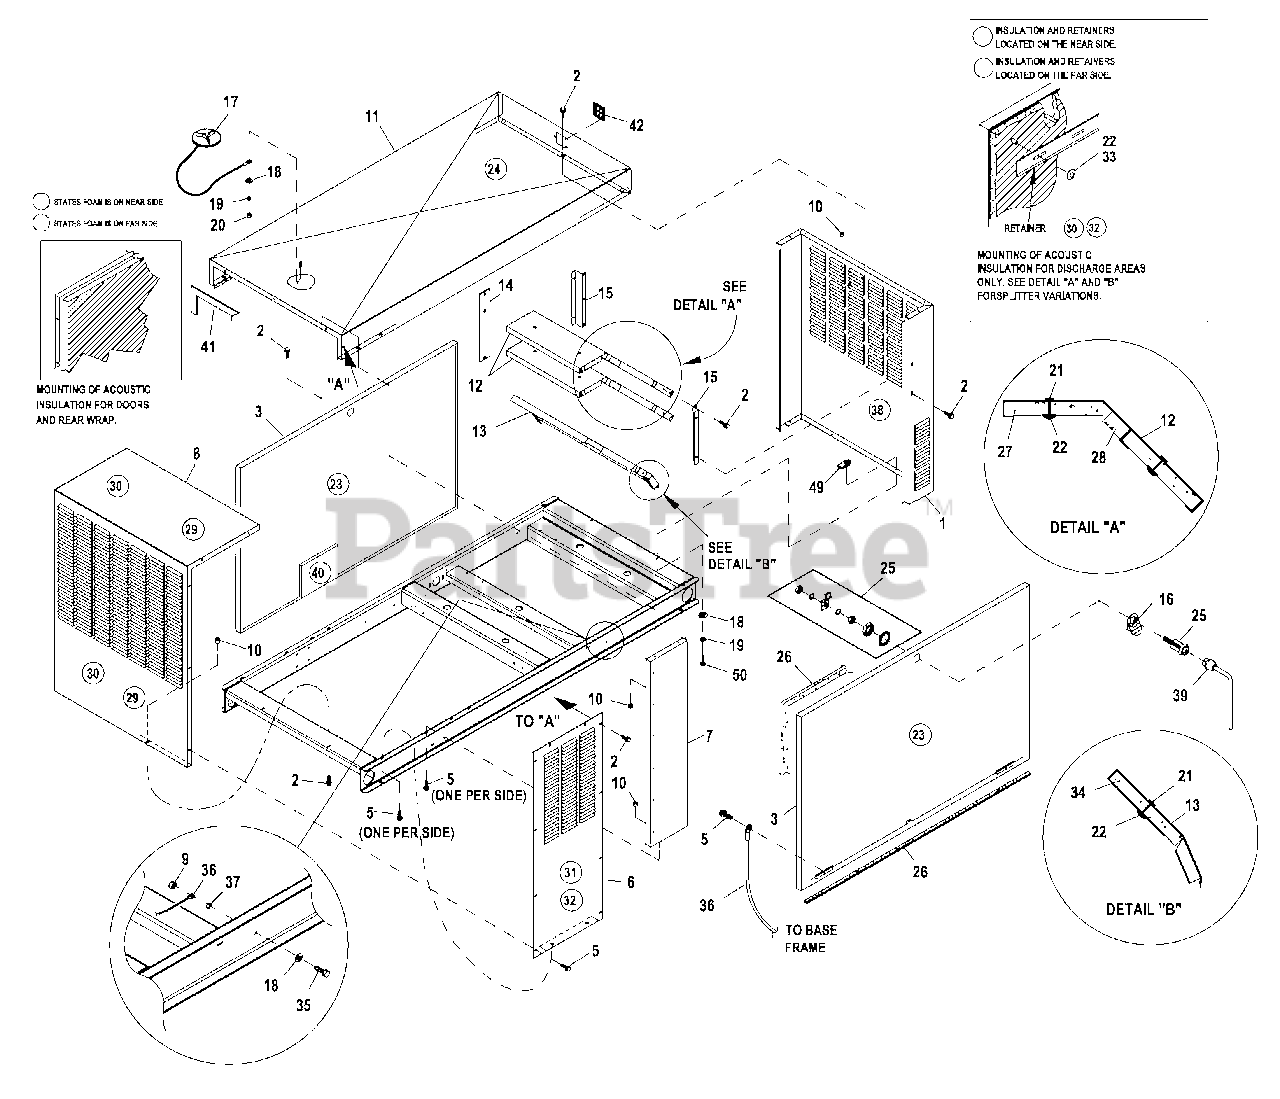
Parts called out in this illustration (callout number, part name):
1	REAR WRAP C2 CPL
2	SCREW THF M6-1 X 16 N WA Z/JS
3	D OOR C2
4	RIVET PO P .1875 X . 450 SS
5	SCREW TH-FRM M6 W/CAP SHKPRF W
6	DISCHARGE DUCT LH & RH SI D E C2
7	FRONT CORNERS C2
8	DISCHARGE CENTER DUCT C2
9	NUT HEX M 6X 1 .0 G8 YELCHR
10	NUT HEX LOCK M6-1.0 SS NY INS
11	ROOF C2
12	SLITTER C4
13	SPLITTER LOWER C4
14	SPLITTER STINGER C2
15	SUPPORT SPLITTER LHC2
16	TAB PULL
17	ASSEMBLY COVER ACCESS
18	WASHER FLAT 1/4-M6 ZINC
19	WASHER LOCK M6-1/4
20	NUT HEX 1/4-20 STEEL
21	INSULATION RETAINMENT HANGER
22	WASHER SELF LOCKING DOME #4-40
23	INSULATION D OOR C2
24	INSULATION ROOF TOP
25	VISE-ACTION LATCH SLOTTE D CIR
26	GASKET EXTRUDED TRIM (328" LG)
27	INSULATION SPLITTER
28	INSULATION SPLITTER
29	INSULATION D UCT
30	RETAINER INSULATION (820)
31	INSULATION D UCT SI D ES
32	RETAINER INSULATION (450)
33	WASHER SELF LOCKING DOME #8-32
34	INSULATION LOWER SPLITTER
35	SCREW HHC M6-1.0X 20 G8.8
36	ASSY WIRE 14 AWG 34.8" GRN/YEL
37	WASHER SHAKEPROOF INT 1/4
38	INSULATION REAR WRAP
39	KEY VISE-ACTION LATCH SLOT CIR
40	FOAM 300 X 300 THERMAL ACO (APPLIES TO 4.2L UNITS ONLY)
41	STRIP SEALANT 1/8X 1 (44.52"LG)
42	RF COVER PLATE-PLASTIC-BISQUE
49	NUT UM6-1.0 GEOMET
50	SCREW HHFC M6-1.0 X 2 0 G8.8
